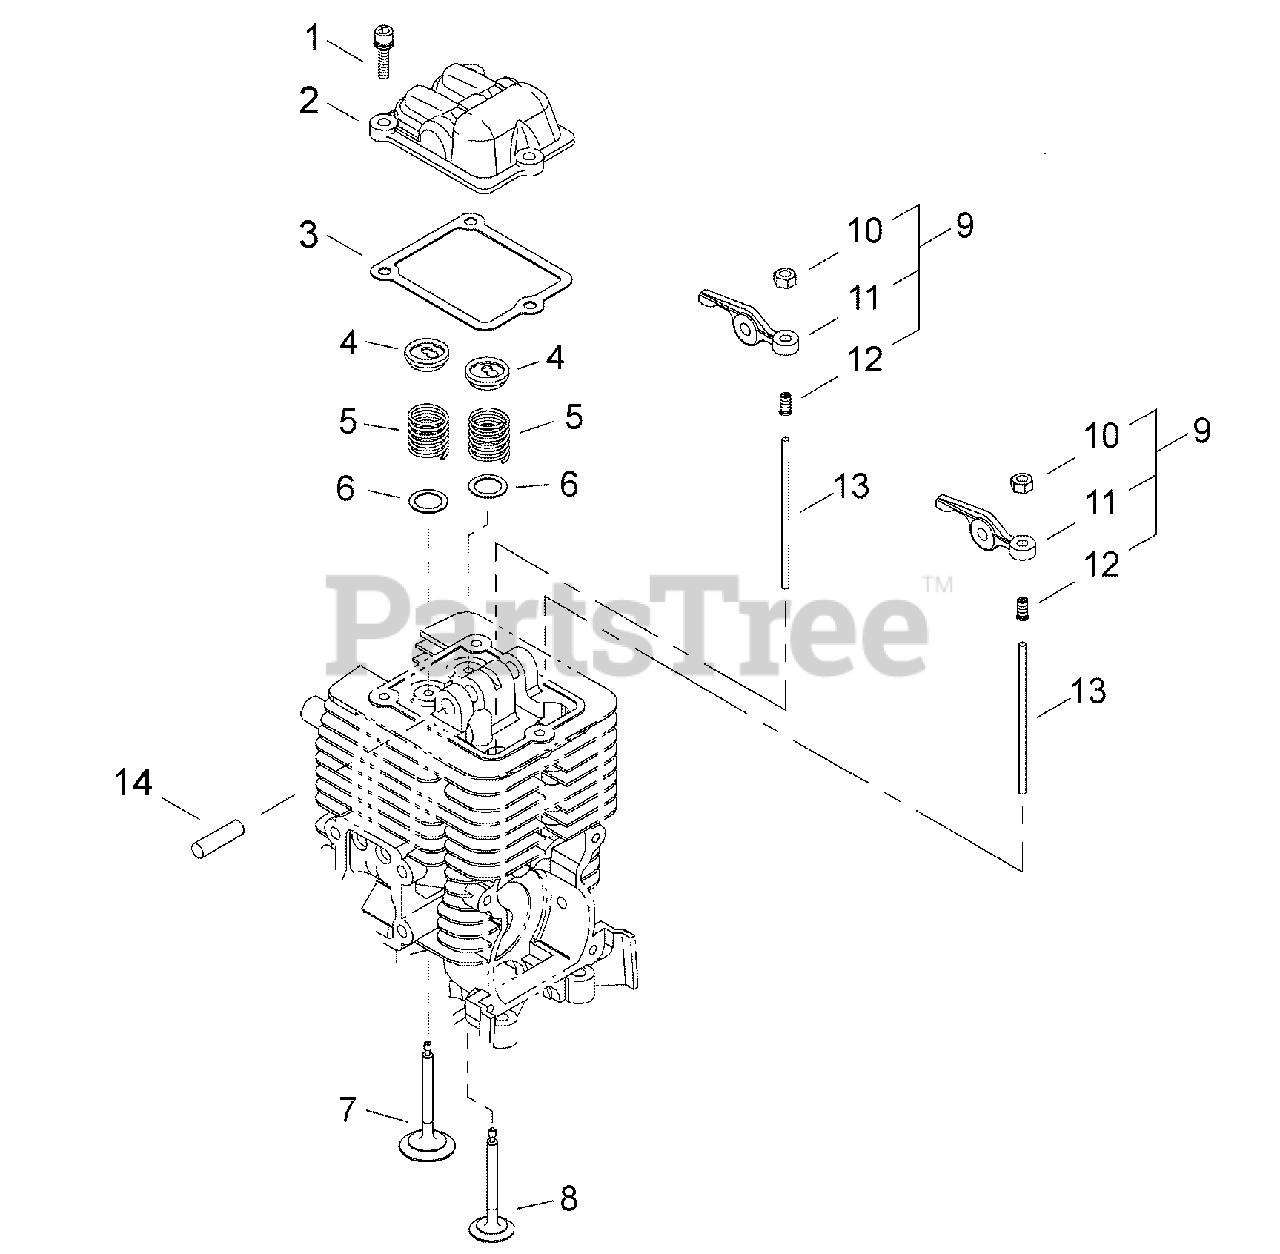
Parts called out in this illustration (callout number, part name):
1	BOLT M4×14
2	COVER, ROCKER ARM
3	GASKET, ROCKER ARM
4	RETAINER, VALVE
5	SPRING, VALVE
6	WASHER, VALVE 9
7	VALVE, INTAKE
8	VALVE, EXHAUST
9	ARM ASSY, ROCKER
10	NUT, ADJUSTER LOCK 5
11	ARM, ROCKER
12	SCREW, ADJUSTER
13	PUSHROD
14	SHAFT, ROCKER ARM Ø5×37.8 MM
